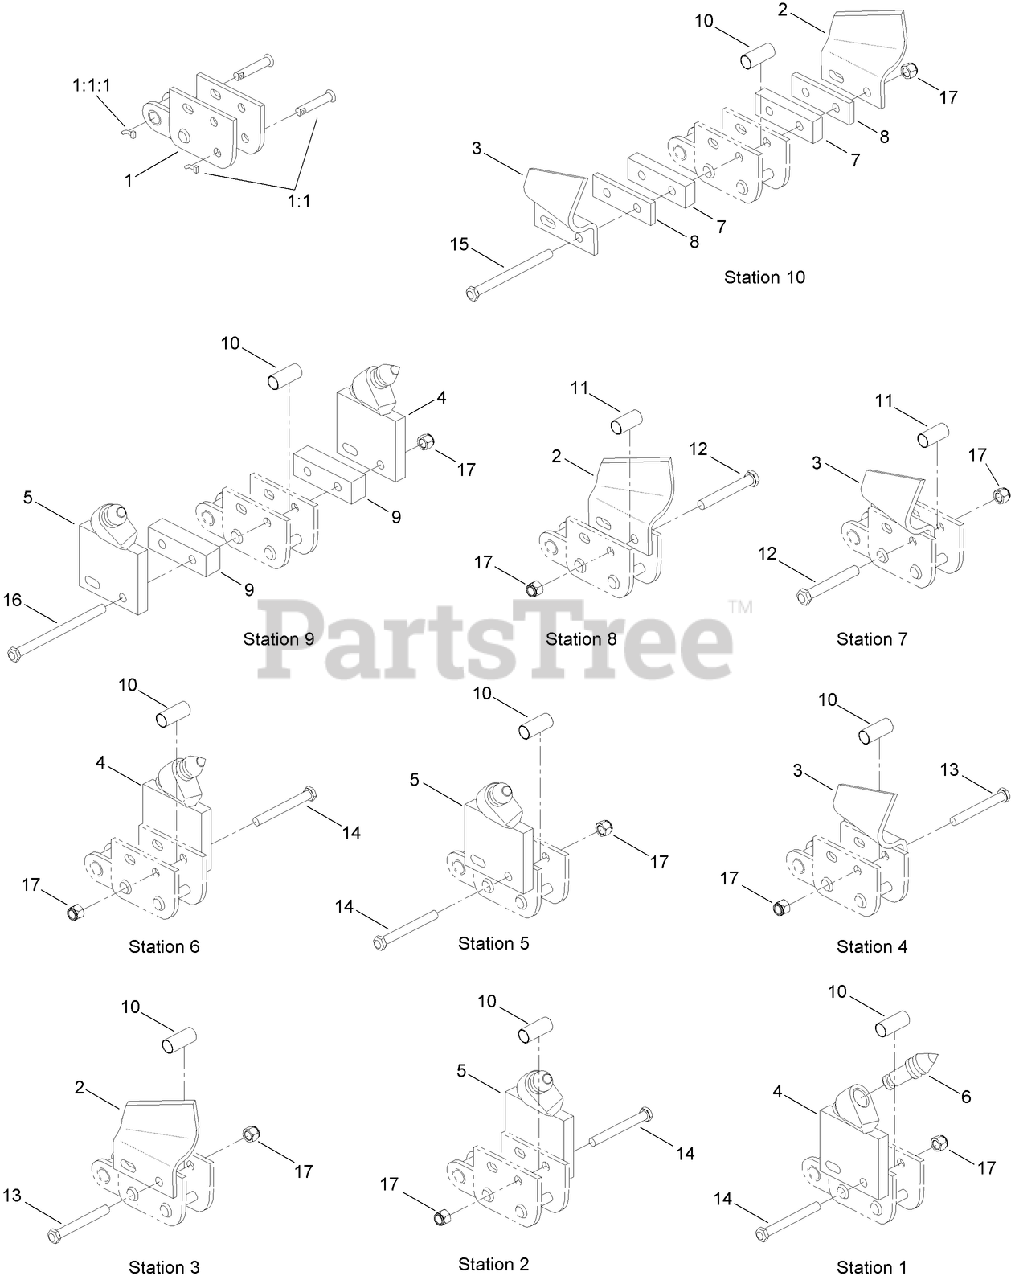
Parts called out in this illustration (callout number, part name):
1	CHAIN REPAIR LINK ASM
1:1	NOTCHED PIN AND KEEPER ASM
1:1:1	PIN-KEEPER
2	CUTTER-CUP, LH
3	CUTTER-CUP, RH
4	HOLDER-BIT, LH
5	HOLDER-BIT, RH
6	BIT AND CLIP, CARBIDE
7	SPACER-FLAT (.500 Inch)
8	SPACER-FLAT (.250 INCH)
9	SPACER-FLAT (1.00 INCH)
10	SPACER-TUBE, OUTSIDE MOUNT
11	SPACER-TUBE, INSIDE CUP MOUNT
12	BOLT-HH
13	BOLT-HH
14	BOLT-HH
15	BOLT-HH
16	BOLT-HH
17	NUT-LOCK
